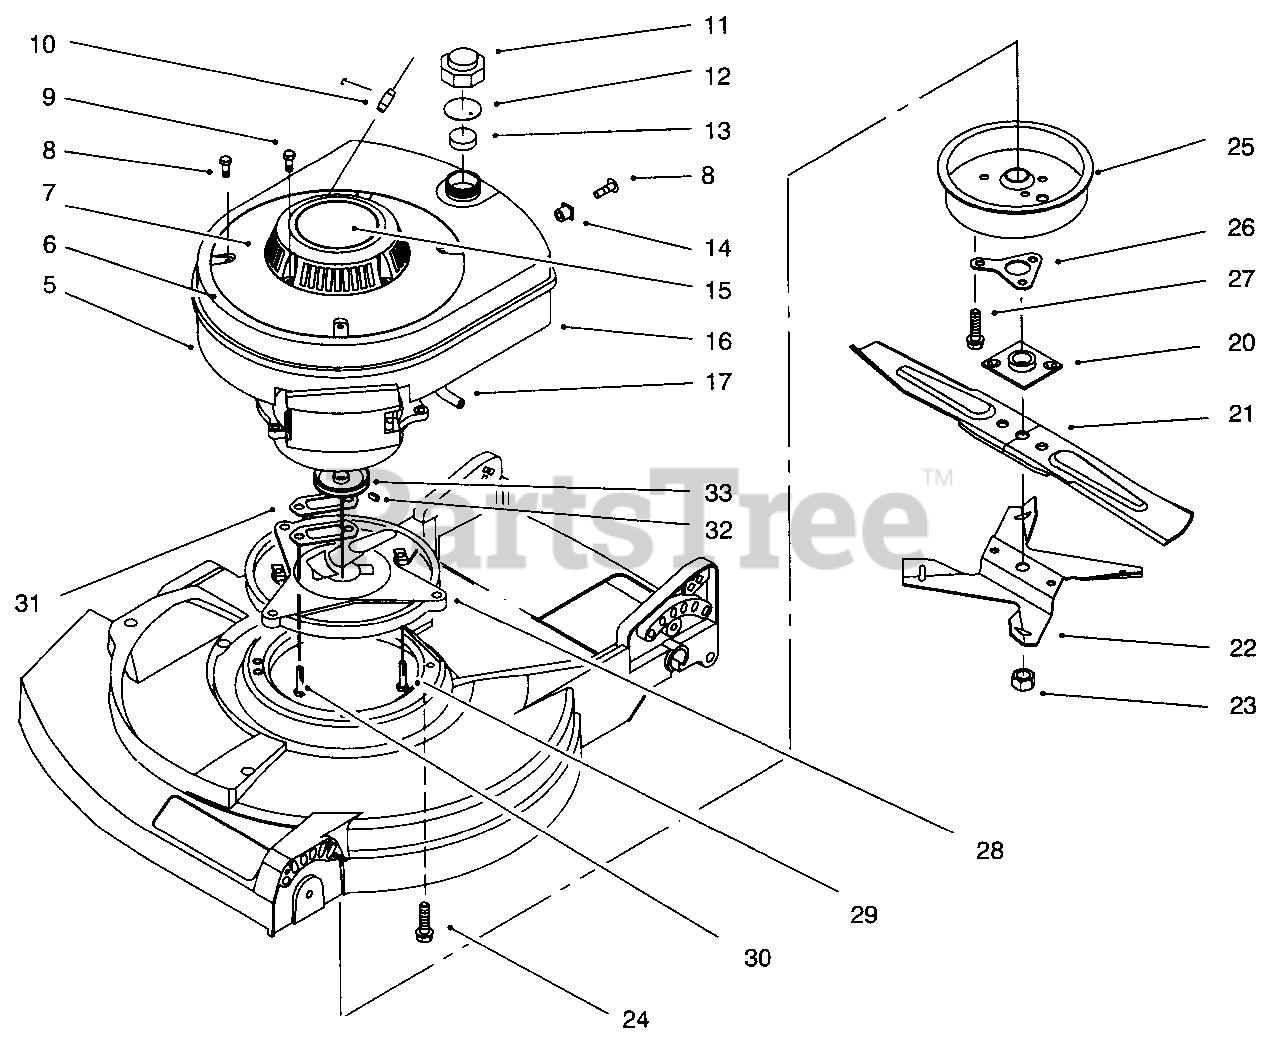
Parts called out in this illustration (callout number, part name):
5	Shroud & Tank Assembly
6	Base-Starter
7	Starter Assembly
8	Screw-Self Tapping
10	Stop-Rope
11	Cap-Fuel
12	Gasket-Fuel Cap
13	Baffle Fuel Cap
14	Grommet
15	Decal-Recoil (Model No. 10422)
16	Engine Assembly
17	Line-Fuel
20	Plate & Collar Assembly
21	Blade 21"
22	Fan-Mulching
23	Nut-Blade
24	Screw-Engine
25	Muffler Cover Assembly
26	Support-Crankshaft
28	Plate-Muffler
31	Gasket-Muffler
32	Screw-Set (Model No. 10518 & 10523)
33	Pulley (Model No. 10518 & 10523)
